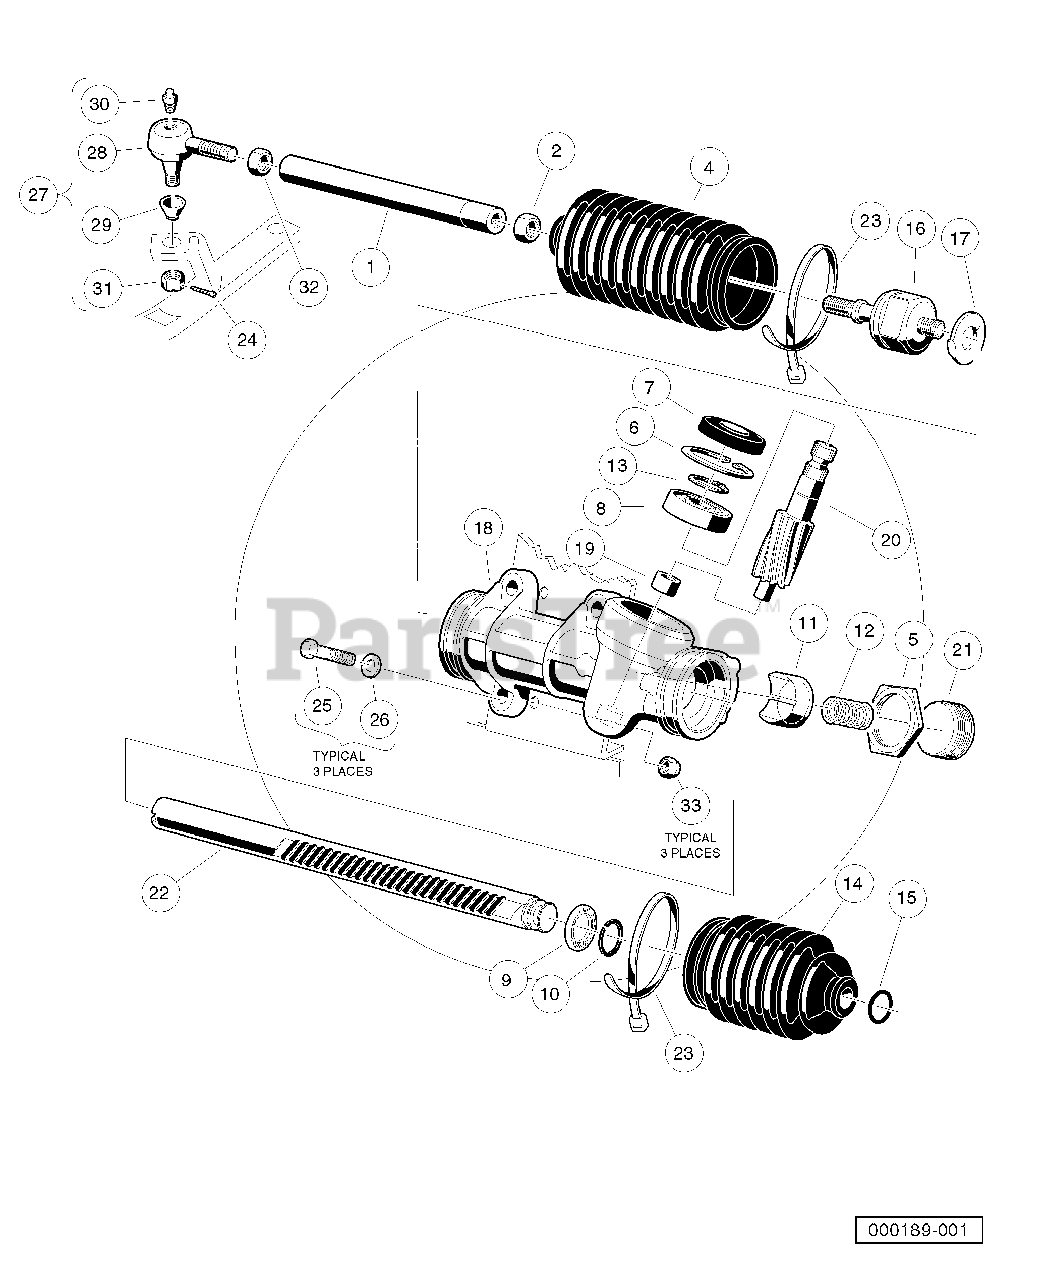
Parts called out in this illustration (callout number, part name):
1	Link, Rack and Pinion Drag
2	Nut, 12mm Hex
3	Steering Gear Assembly
4	Bellows, Long
5	Rack Screw Locknut
7	Seal, Steering Pinion Dust
8	Bearing, Ball
9	Stop Washer
10	Stop Ring, C-Type
11	Support Yoke
12	Rack Guide Pressure Spring
13	Ring, Stop, C-Type
14	Bellows, Short
15	Dust Seal Retaining Ring
16	Inner Ball Joint Asm
17	Washer, Tab
18	Box, Steering Gear
19	Bearing, Lower Pinion
20	Pinion, Steering
21	Screw, Rack Guide
22	Rack, Steering
23	Tie Wrap, 8" Nylon
24	Pin, 3/32 X 1.00 Sq Cut Cotter
25	Screw, 3/8-16 X 1.50 Hex-Head Cap
26	Washer, 3/8 Type A Flat
27	Ball Joint, Left
28	Socket, LH Vertical
29	Seal, Vertical Socket Dust
30	Fitting, 1/4-28 Thread-Forming Grease
31	Nut, 3/8-24 UNF Hex
32	Nut, 1/2-20 Hex, Left-Hand Thread
33	Locknut, 3/8-16 Hex
